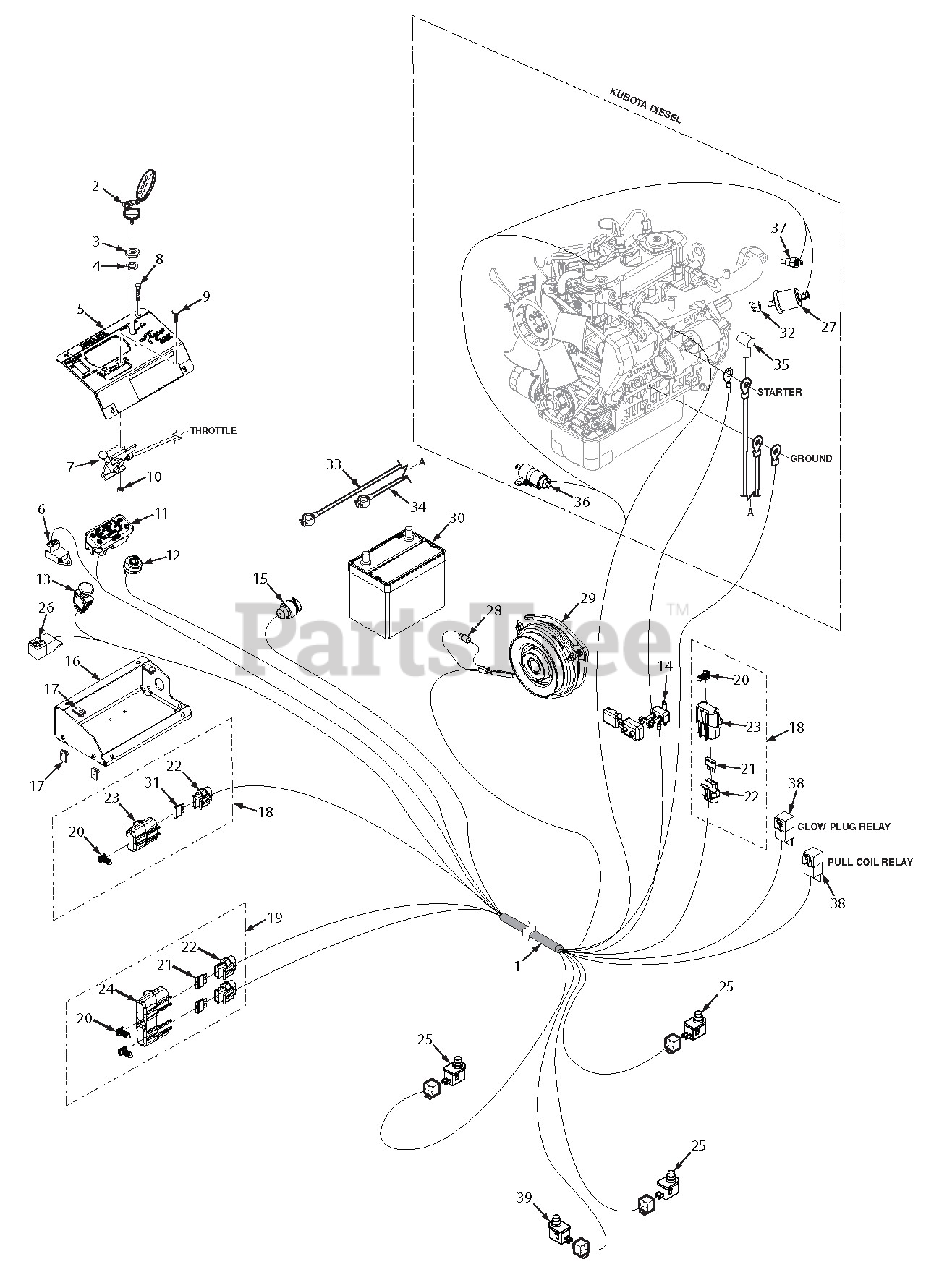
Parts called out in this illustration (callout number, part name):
1	Wire Harness, STTII-25KBD
2	Key Assy., w/Fob
3	Nut, Hex 5/8-32
4	Lockwasher, 5/8 Internal
5	Instrument Panel w/Decal
6	Timer, Glow Plug
7	Control Cable, Throttle
8	Capscrew, 1/4-20 x 3/4"
9	Bolt, Carriage 10-24 x 1/2"
10	Lock Nut, #10-24
11	Cluster Gauge
12	Key Switch
13	Switch, PTO
14	50 Amp Breaker
15	Power Plug, 12V
16	Base, Instrument Panel
17	U-Nut, 1/4-20
18	Single Fuse Assy., Excluding Fuse
19	Double Fuse Assy.
20	Clip, Wire
21	Fuse, 20 Amp
22	Fuse Holder
23	Cover, Sealed Single
24	Cover, Sealed Double
25	Switch, N/O
26	Relay
27	Sender Unit, Oil Pressure
28	Diode, 600V - 6A
29	Clutch Assembly, GT3.5
30	Battery, 525 CCA
31	Fuse, 5 Amp
32	Elbow, 45 Degree Street
33	Battery Cable, 14" Red w/Braid
34	Battery Cable, 21" Black
35	Rubber Boot
36	Solenoid, Fuel Shut-Off
37	Sender Unit, Water Temp.
38	Relay
39	Plunger Switch, Single Pole
